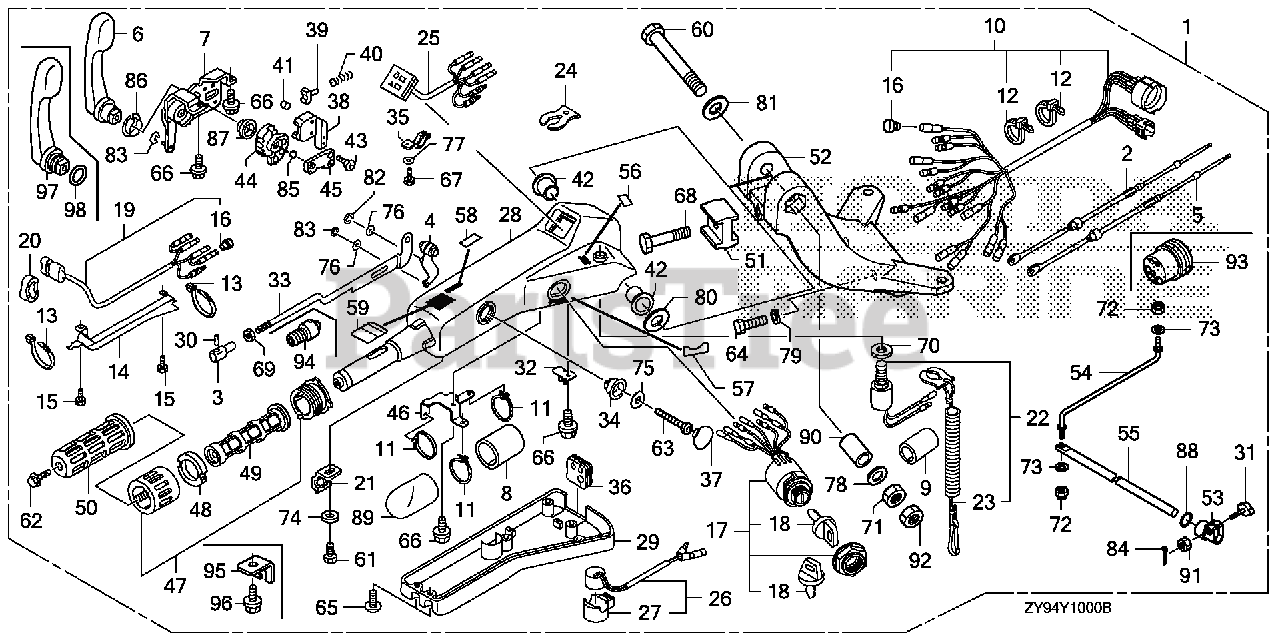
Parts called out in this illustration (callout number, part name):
1	HANDLEBAR KIT *NH282MU* (OYSTER SILVER METALLIC-U)
2	CABLE, THROTTLE
3	PIVOT, THROTTLE CABLE
4	ARM, THROTTLE
5	CABLE, SHIFT
6	LEVER, SHIFT
7	FRAME ASSY., SHIFT
8	TUBE (38.1X40)
9	TUBE
10	CABLE ASSY., LONG HANDLE (A)
11	BAND (CONVEX CV-150)
12	BAND (CONVEX CV-200)
13	BAND (CONVEX)
14	COVER, WIRE
15	SCREW
16	PLUG, CONNECTOR (INNER) (TROLLING CONTROL)
17	SWITCH ASSY., COMBINATION
18	KEY ASSY., COMBINATION SWITCH (35100-ZV5-003 ONLY) DUAL QTY = (4) (SINGLE)
19	SWITCH ASSY., POWER TILT
20	GROMMET
21	HOLDER, SWITCH
22	SWITCH ASSY., EMERGENCY STOP
23	WIRE, EMERGENCY (SINGLE) (DUAL)
24	CLIP, EMERGENCY LOCK
25	LAMP ASSY., INDICATOR
26	BUZZER ASSY., WARNING
27	SUSPENSION, WARNING BUZZER
28	HOUSING *NH282MU* (OYSTER SILVER METALLIC-U)
29	COVER, HANDLEBAR (LOWER)
30	PIN, THROTTLE CABLE
31	BOLT, FRICTION
32	BRACKET, CABLE
33	PLATE ASSY., LOCK
34	STOPPER
35	PLATE, GUIDE
36	GROMMET
37	CAP
38	GUIDE, SPRING
39	ACTUATOR
40	SPRING, COIL
41	ROLLER
42	BUSH, HANDLEBAR
43	SCREW (M5X14)
44	GEAR, SHIFT
45	PLATE, BALL GUIDE
46	BRACKET
47	GRIP ASSY., THROTTLE FRICTION
48	PAD, THROTTLE FRICTION
49	PIPE, GRIP
50	RUBBER, GRIP
51	BLOCK, HEIGHT ADJUSTER
52	BRACKET B, STEERING *NH282MU* (OYSTER SILVER METALLIC-U)
53	BLOCK, STEERING FRICTION
54	ROD, STEERING FRICTION
55	SHAFT, STEERING FRICTION
56	MARK, EMERGENCY SWITCH INDICATION
56	MARK, EMERGENCY SWITCH INDICATION (EU)
57	MARK, STARTER (ENGLISH)
58	MARK, CHANGE (JAPANESE/ENGLISH)
59	MARK, THROTTLE (ENGLISH)
60	BOLT, HEX. (12X80)
61	BOLT (M5X8)
62	BOLT, FLANGE (6X12) Use from Frame SN 1005249.
63	BOLT (M8X50)
64	BOLT, HEX. (10X32)
65	BOLT (M5X12)
66	BOLT (M6X12)
67	BOLT (M5X12)
68	BOLT, FLANGE (8X28)
69	NUT, HEX. (5MM)
70	NUT, HEX. (16MM) DUAL QTY = (2) (SINGLE)
71	NUT, HEX. (12MM)
72	NUT, SELF-LOCK (8MM)
73	WASHER, PLAIN (8MM)
74	WASHER (5MM)
75	WASHER (8MM)
76	WASHER (10MM)
77	WASHER (5MM)
78	WASHER, WAVE (14MM)
79	WASHER (10MM)
80	WASHER, PLAIN (12MM)
81	WASHER, PLAIN (12MM)
82	E-RING
83	E-RING
84	PIN, SPLIT (2.0)
85	BALL, STEEL
86	BEARING
87	BEARING
88	O-RING (15.54X2.26)
89	TUBE, CORD (40MM)
90	COLLAR, DISTANCE (12.2X23X16)
91	NUT, HEX. (6MM)
92	NUT, HEX. (12MM)
93	GROMMET, HANDLEBAR CABLE
94	ROD, GROMMET
95	CLAMP, BRACKET
96	BOLT (M6X12)
97	LEVER, SHIFT
98	O-RING (20.6X1.9)
